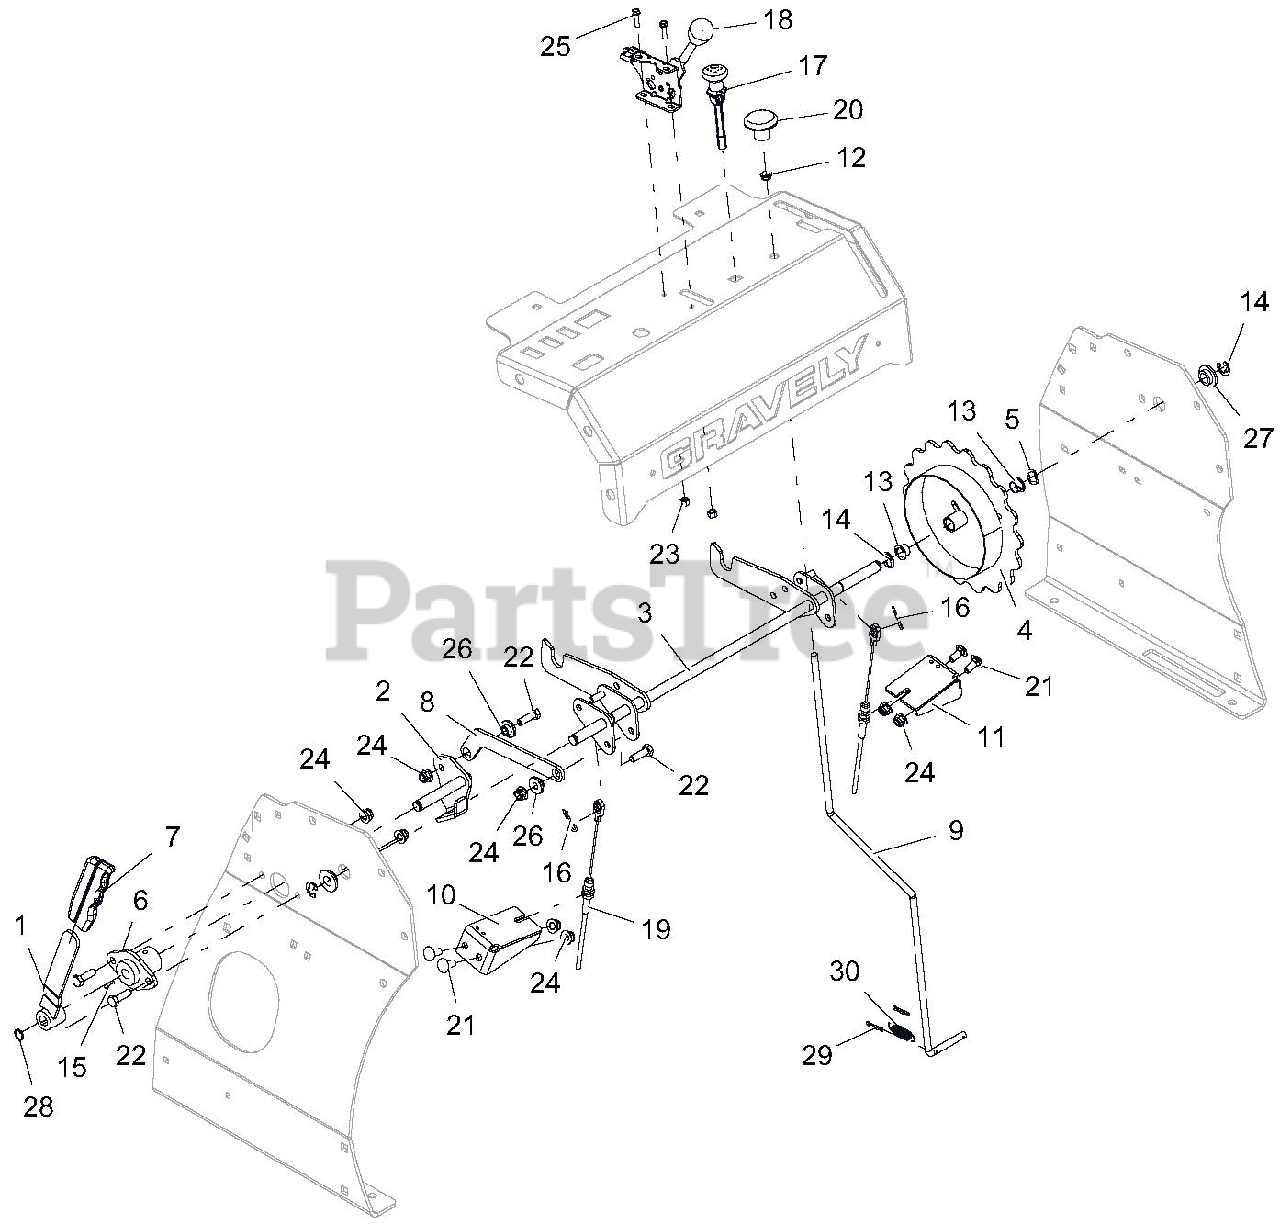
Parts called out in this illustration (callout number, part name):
1	WLDMT, PARKING BRAKE LEVER
2	WLDMT, PARKING BRAKE ACTUATING
3	WLDMT, BRAKE INTERLOCK
4	WLDMT, HEIGHT OF CUT
5	WAVE WASHER .531X.781X.125 FH
6	BSHG, FLANGE .500 ID
7	GRIP, PARKING BRAKE
8	LINK, INTERLOCK
9	WIREFORM, TRAILER LOCK
10	BRKT, CABLE MTG.
11	BRKT, LH CABLE MTG
12	BSHG, POLYLINER-.38 SNAPIN
13	BUSHING, POLYLINER - .50 SPLIT
14	RG-RTNG-EXT .500X.042 (E)
15	KEY, WDRF .13x.63 HRD#5 GM124545 P
16	PIN, HAIR INT .08X.18X1.18 YWZC
17	CABLE, CHOKE
18	CABLE, PRO-CONTROL THROTTLE
19	CABLE, PROSTANCE P. BRAKE
20	KNOB, PUSH -PULL .312-18
21	BLT-RDHDSQNK .31-18X.75 G5 YWZC
22	BLT-HEX .31-18X1.00 GR5 YWZC
23	NUT-LK-NYL #10-24 YWZC
24	NUT-LK-NYL-FLG .31-18 YWZC
25	@SCR-MCH 10-24X.75 HWH YWZC
26	BSHG, FLG .32X.500.344X.880
27	BSHG, FLANGE .515X.750X.31X1.12
28	RG-RTNG-EXT .500x.050
29	PIN-HAIR, ENDRIES #25 YWZC
30	SPRG, EXTENSION
